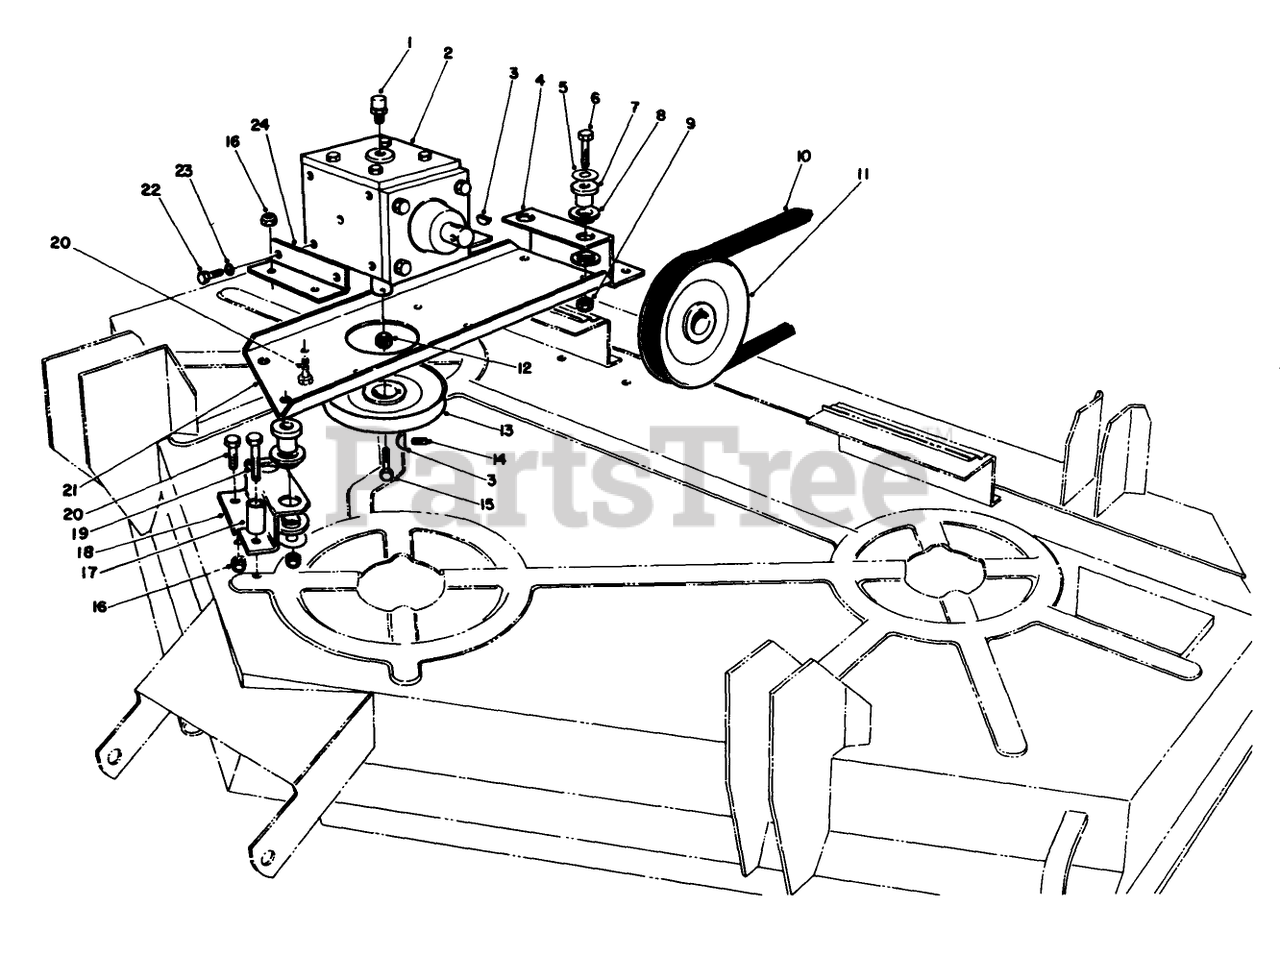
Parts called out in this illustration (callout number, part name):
1	FITTING-LUBE
2	Gear Box
4	PLATE BRACKET R
5	WASHER
6	SCREW-HH
7	MOUNT
8	INSERT
9	NUT-LOCK, NI
10	V-BELT
11	PULLEY - INPUT
12	NUT-LOCK, NI
13	PULLEY - OUTPUT
14	SCREW-SET, SQH
15	SCREW-HH
16	NUT-LOCK, NI
17	Spacer
18	PLATE BRACKET R
19	SCREW-HH
20	SCREW-HH
21	PLATE - MTG GEAR BOX R
22	SCREW-HH
23	WASHER-LOCK
24	ANGLE - GEAR BOX MTG R
